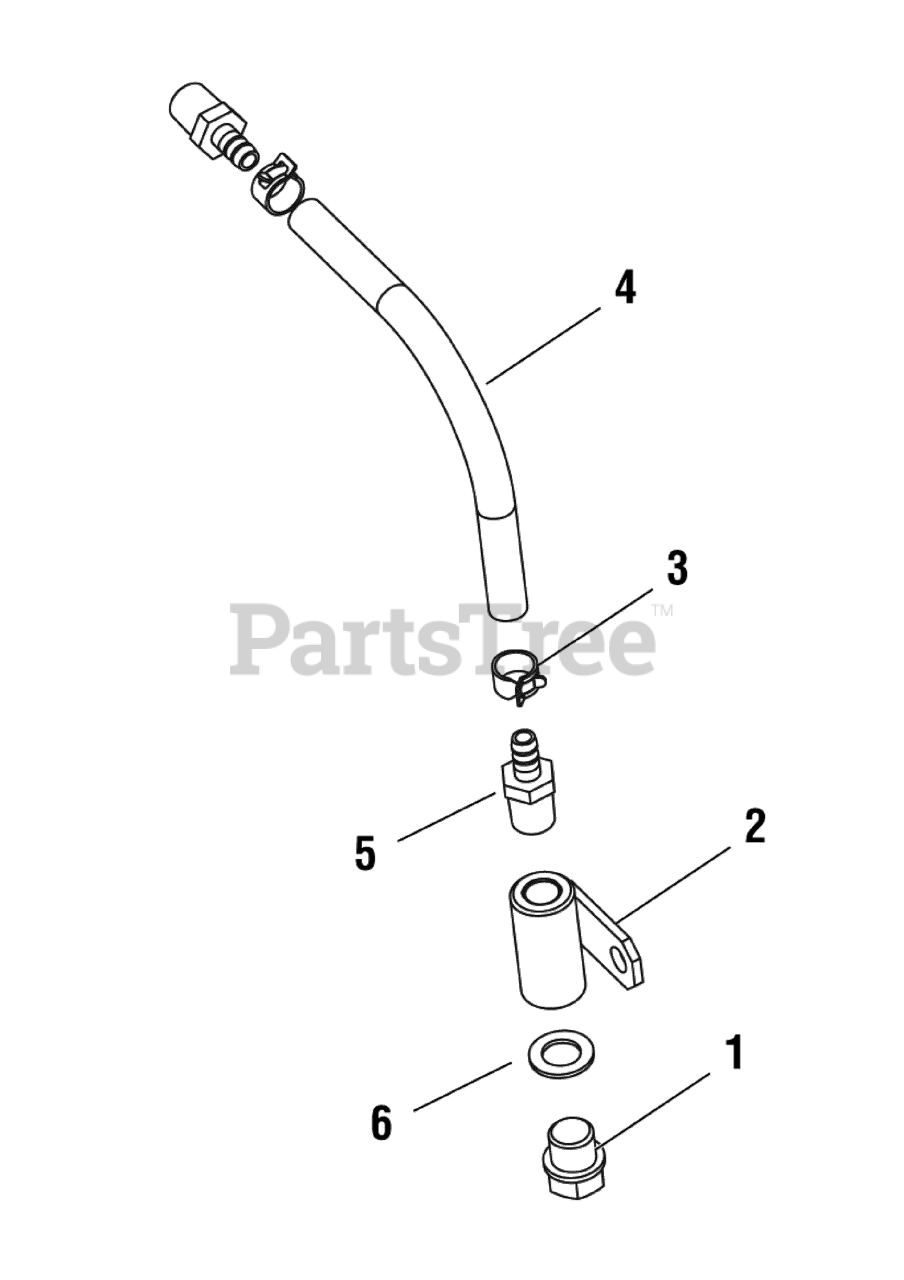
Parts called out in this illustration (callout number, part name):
1	PLUG, Hex Head, M14 x 1-1/2
2	NOZZLE
3	CLAMP, Spring
4	HOSE, Oil
5	TAPER JOINT
6	WASHER, Oil Plug
